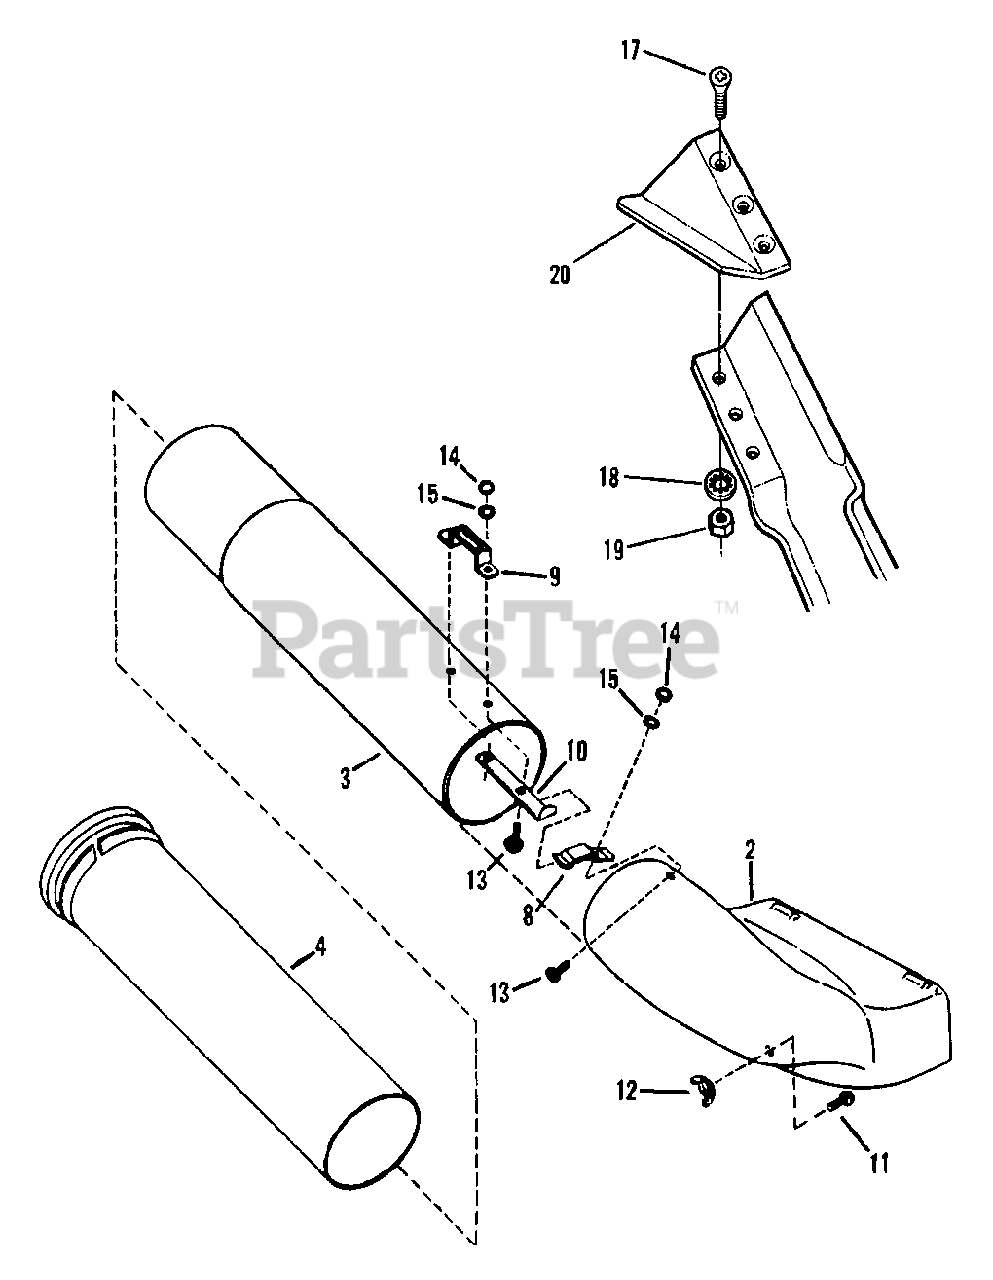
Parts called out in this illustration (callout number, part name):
2	ASSEMBLY, Deck Adapter/Decal
3	TUBE, Grass (8" Diameter
4	TUBE, Grass (10" Diameter)
8	LATCH, Tube
9	HANDLE, Tube
10	BASE, Tube Handle
11	BOLT, 5/16-18 x 1" Short Neck Carriage, Grade 5
12	WING-NUT, 5/16-18
13	BOLT, 1/4-20 x 3/4" Short Neck Carriage, Grade 5
14	NUT, 1/4-20
15	WASHER, 1/4" Internal Tooth Lock
16	WASHER, 5/16" Flat
17	SCREW, 5/16-24 x 11/16" Oval Head Machine
18	WASHER, 5/16" Internal Tooth Lock
19	NUT, 5/16-24 Hex
20	AIR LIFT
